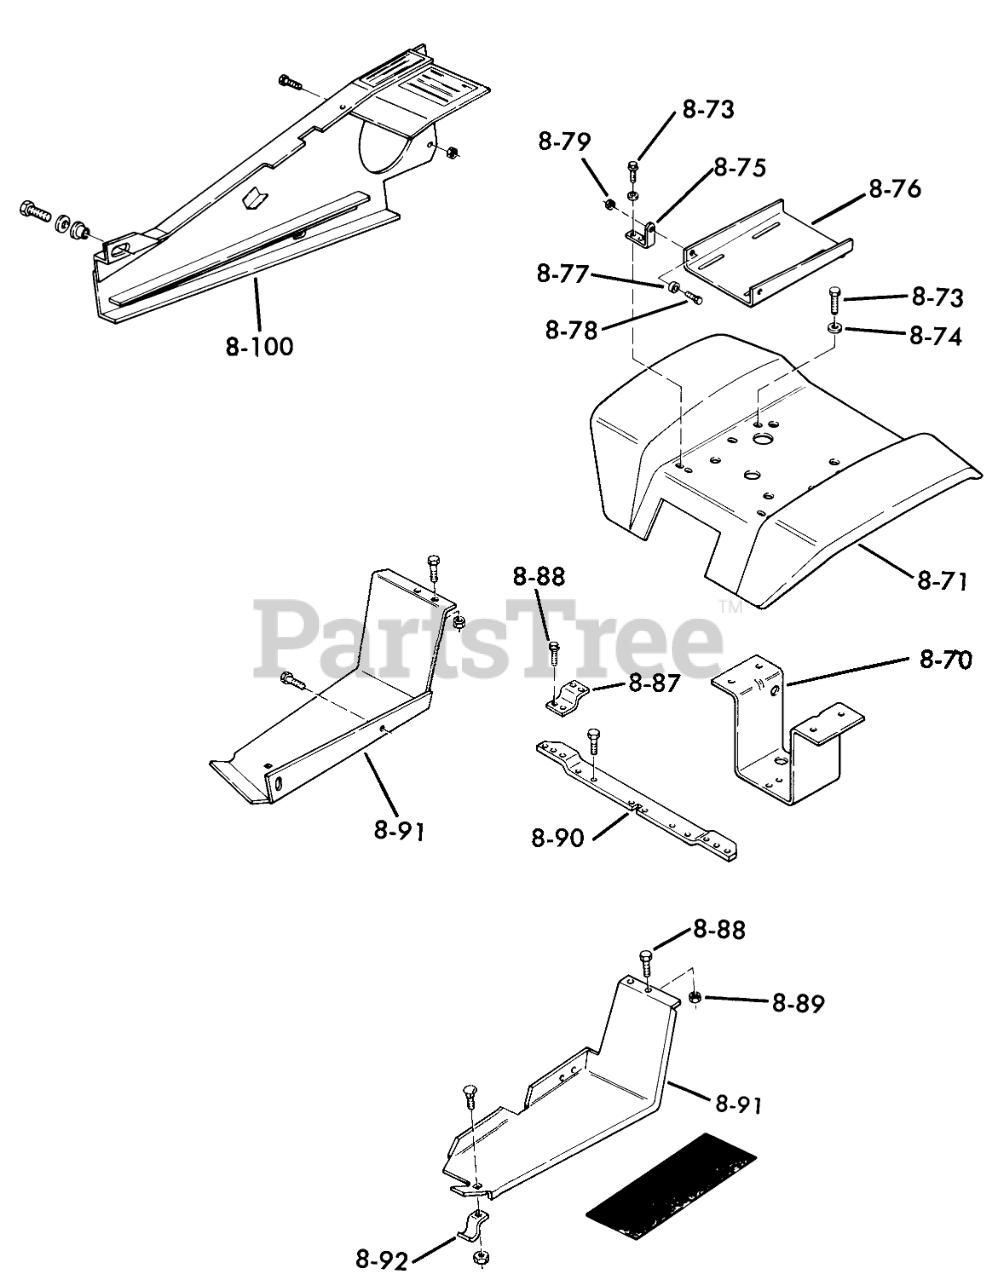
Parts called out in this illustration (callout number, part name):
8-70	Bracket-Fender
8-71	Fender
8-71	Bushing
8-73	Bolt
8-74	WASHER 5/16 SAE
8-75	BRACKET-PIVOT
8-76	Plate Seat Pivot
8-77	BUSHING
8-78	HHCS
8-79	Nut
8-79	BUMPER-RUBBER
8-87	BRACKET-FENDER R
8-88	HHCS
8-88	Nut
8-88	Bracket-Footrest
8-88	SCREW
8-91	Footrest-LH
8-91	Footrest-L.H.
8-91	PAD-FOOTREST
8-91	Bolt
8-91	Nut
8-91	Screw
8-92	BRACKET
8-92	Bolt
8-92	Nut
8-92	Bracket
8-100	Belt Guard
8-100	H H C S
8-100	Screw
8-100	LOCKWASHER
